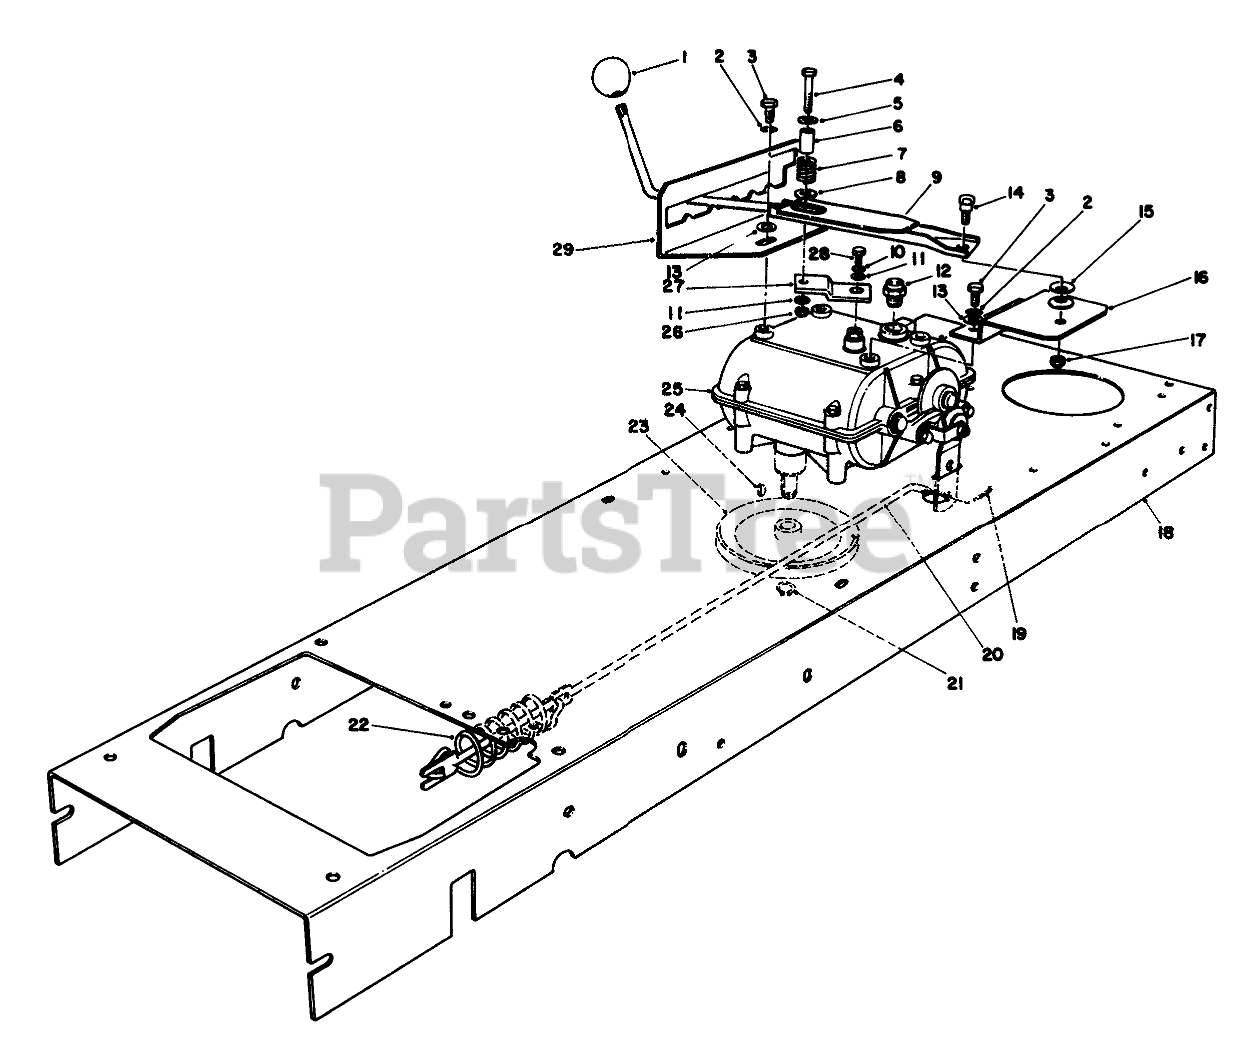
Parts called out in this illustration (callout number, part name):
2	WASHER-LOCK
3	SCREW-HWHTF
4	SCREW-HH
5	WASHER-FLAT
6	SPACER-SPLIT
7	SPRING-COMPRESSION
8	WASHER-FLAT
9	SHIFT LEVER WA B
10	WASHER-LOCK
11	WASHER-FLAT
12	NEUTRAL SWITCH
13	WASHER-PLAIN
14	SCREW-SHOULDER
15	WASHER-BELLEVILLE
16	SHIFT MTG BRKT
17	NUT-LOCK, NI
18	Frame-Main
19	PIN-COTTER
20	BRAKE ROD
21	RING-SNAP, EXTERNAL
22	SPRING-EXT
23	PULLEY
24	KEY-WOODRUFF
25	TRANSMISSION
26	NUT-LOCK, CONE
27	LEVER-SHIFT
28	SCREW-HH
29	Gate-Shift
